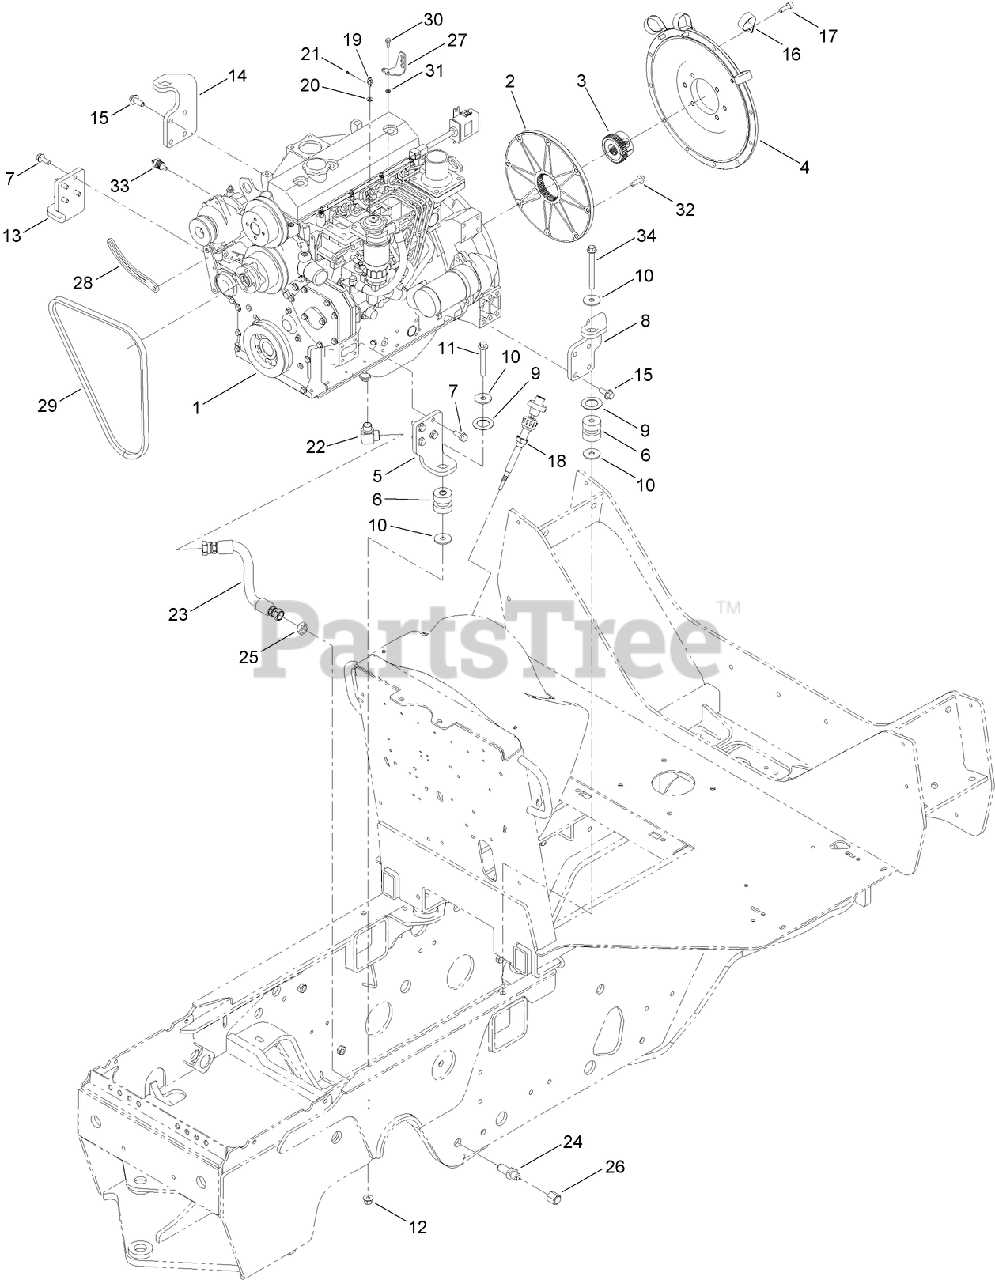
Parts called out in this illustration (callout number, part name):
1	ENGINE-CUMMINS
2	FLANGE-Pump
3	HUB-Pump
4	PLATE-MOUNTING, PUMP
5	PLATE-FRONT ENGINE MOUNT, LH
6	ISOLATOR-MOUNTING, UNIVERSAL
7	SCREW-HHF
8	MOUNT-ENGINE REAR, LH
9	SPACER-ISOLATOR
10	WASHER-THRUST
11	SCREW-HHF
12	NUT-LOCK, HHF
13	PLATE-FRONT ENGINE MOUNT, RH
14	MOUNT-ENGINE REAR, RH
15	SCREW-HHF
16	CLAMP-R
17	SCREW-HSH
18	CABLE-THROTTLE
20	WASHER-FLAT
21	PIN-COTTER
23	HOSE ASM
24	UNION-BULKHEAD
25	NUT-LOCK, BULKHEAD
26	FITTING-CAP
27	BRACKET-THROTTLE
28	BRACKET-ALTERNATOR
29	BELT-Fan
30	SCREW-HHF
31	WASHER-FLAT
32	SCREW-HH
33	SENDER-TEMPERATURE
34	SCREW-HHF
